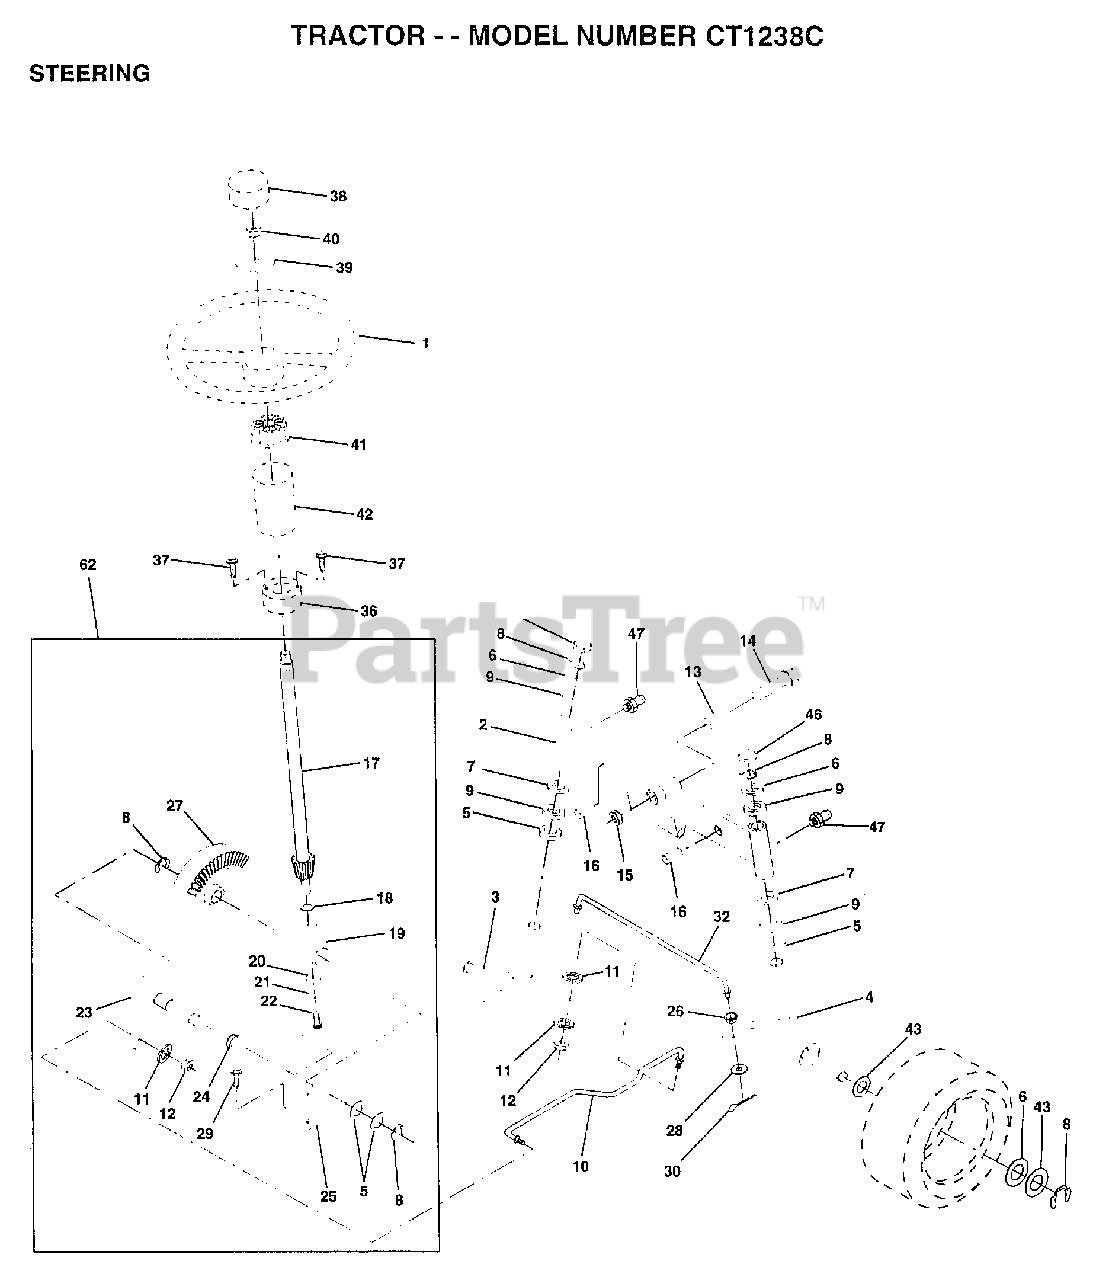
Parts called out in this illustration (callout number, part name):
2	AXLE ASM FRONT
3	SPINDLE LH
4	SPINDLE RH
5	WASHER .T
6	WASHER
7	WASHER
8	RING
9	COL. SRTG. BEAR.
11	LOCKWASHER
13	BEARING
14	BOLT HEX 5/8-11
15	"NUT-LOC,FLANGE LT"
16	AXLE PIN
17	SHAFT ASM
18	THRUST WASHER
19	SUPPORT.SHAFT
21	LOCKWASHER
22	SCREW.SCKTHD.CAP
24	NYLINER T
25	"BRKT,STEERING"
26	BUSHING.DRAGLINK
27	GEAR SECTOR
28	WASHER
29	SCREW
30	COTTER PIN
32	TIE ROD
38	ST WHL INSERT CAP
39	WASHER T
40	GRIPCO NUT
41	ADAPTER-WHEEL LT
42	"TUBE, STR SHAFT"
43	WASHER
46	CAP
47	ZERK M
